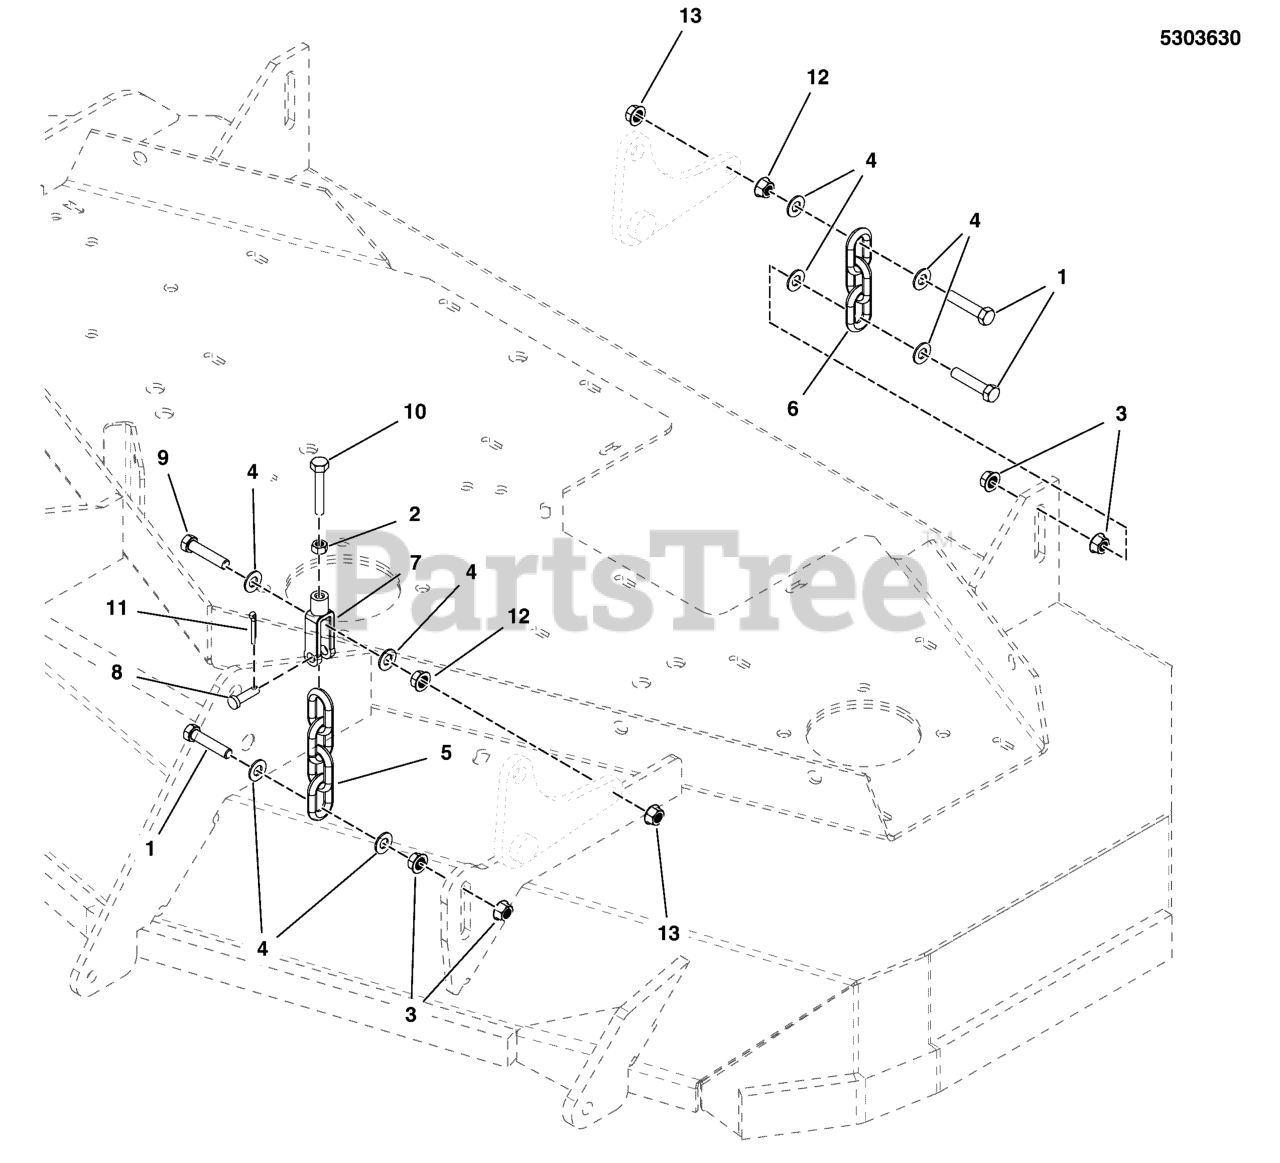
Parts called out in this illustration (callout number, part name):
1	BOLT, 3/8-16 X 1-3/4" GD5 CZ
2	NUT, 5/16-18 HEX JAM
3	NUT, 3/8-16 HEX SERRATED FLANGE
4	WASHER, 3/8 SAE
5	CHAIN, 5/16" GD30, 4 LINKS
6	CHAIN, 5/16 GD30, 3 LINKS
7	CLEVIS, 5/16-18, 3/8 PIN HOLE, CLR ZINC
8	PIN, CLEVIS, 3/8 X 1-1/8, PLATED
9	BOLT, 3/8-16 X 2, GD5, CZ
10	BOLT, 5/16-18 X 2 GD5 TFL
11	PIN, 3/32 X .750, COT, ZINC/CLEAR
12	NUT, 3/8-16 HEX JAM
13	NUT, 3/8-16 HEX NYLOCK FLANGE
